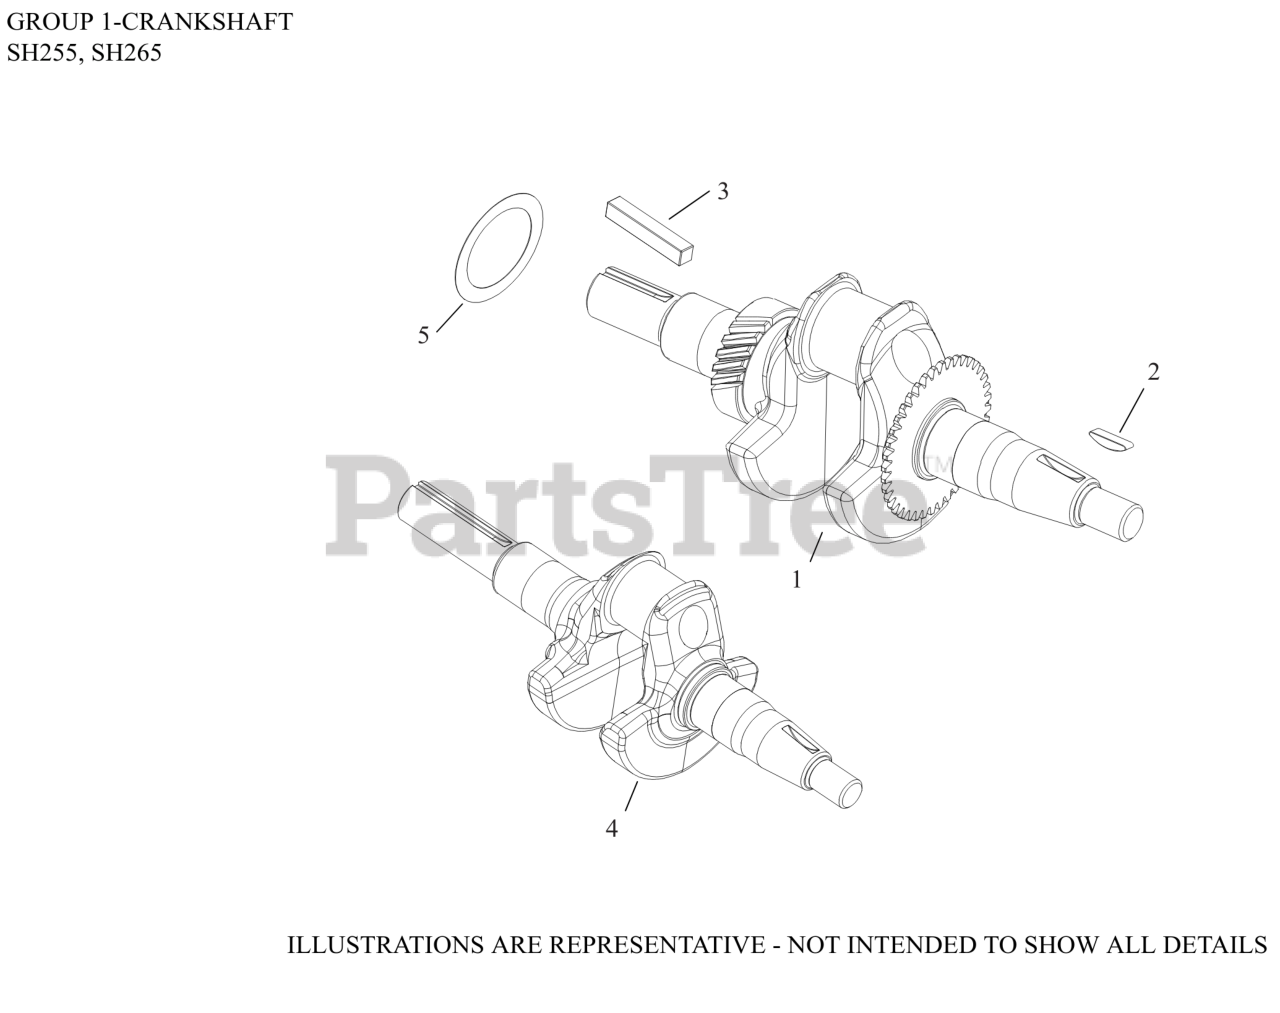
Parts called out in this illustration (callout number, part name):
1	CRANKSHAFT, ASSEMBLY
2	KEY, FLYWHEEL
3	KEY, SQUARE
